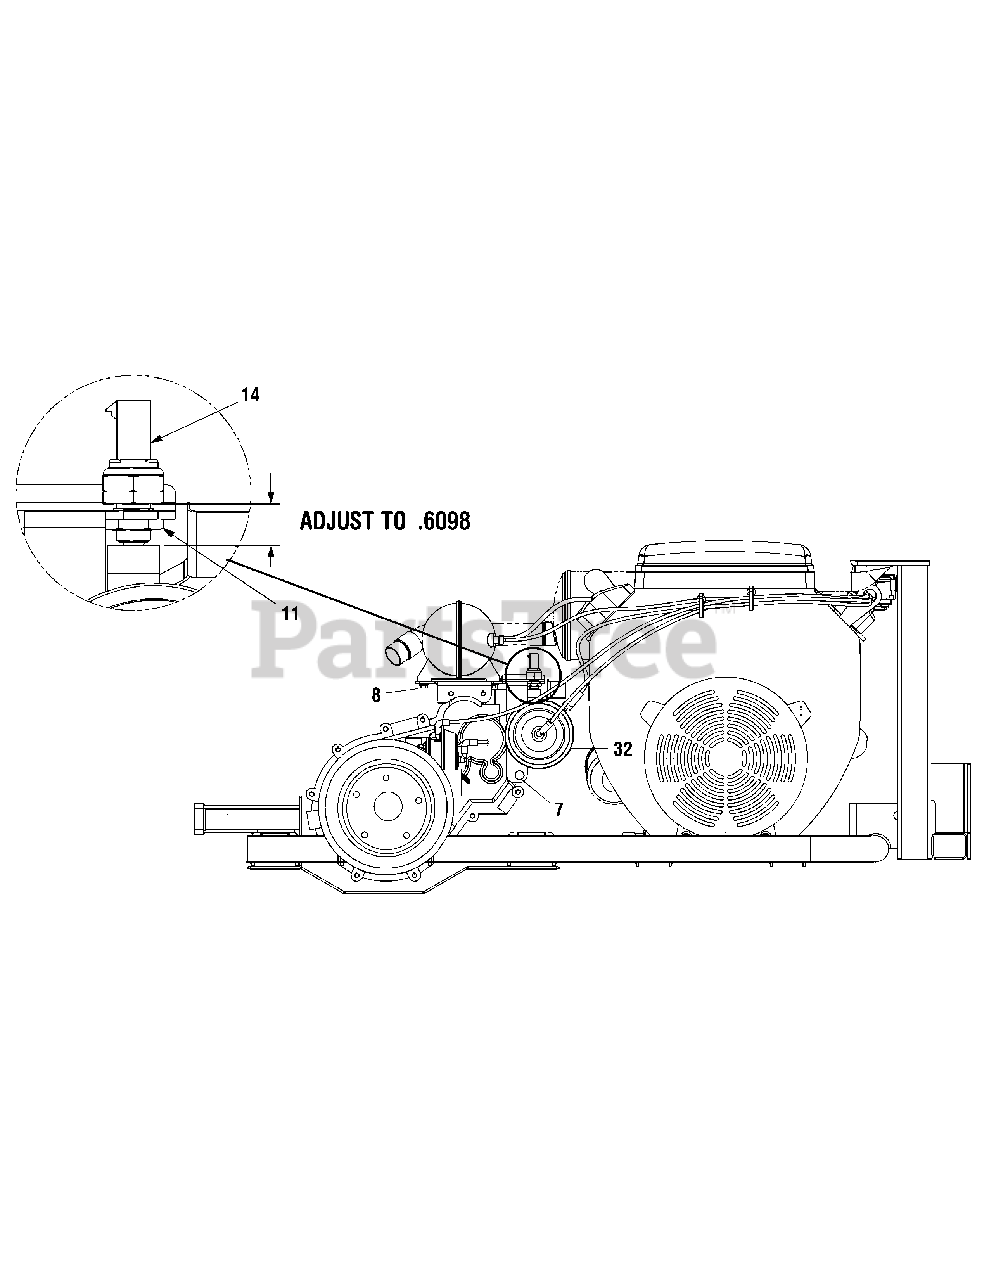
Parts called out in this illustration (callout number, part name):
1	Mounting Bracket, Vacuum Actuator
2	Bracket, Shift
3	Bracket, Vac Relay
4	Screw, 1/4-20 x.5
5	Screw, Hex. #8 - 18 .375
6	Screw, Set, 5/16-24 x .50 LG
7	Screw, 5/16-18
8	Screw, 1/4-14
9	Screw, 5/16-18 x .75 Hex
10	Pin, Yoke 1/4
11	Nut, Hex 9/16-18
12	Pin, Cotter 1/16x.750
13	Yoke, 1/4-28
14	Switch, Neutral
15	Solenoid, Kit Vacuum Actuator
16	Self Threading Nut
17	Clip, Panel Retainer
18	Cable Tie
19	Arm, Shift
20	Hose, Kohler
21	Hose, Manifold Vacuum
22	Hose, Actuator Vacuum
23	Hose, Actuator Vacuum
24	Reservoir, Air
25	Actuator, Vac Differential Lock
26	Differential Lock Vent 3/8 dia.
27	Hose, Vac Differential Lock Supply
28	Cover, Solenoid
29	Flat Washer, .330 x .687 x .030
30	Flat, Washer, .188 x .437 x .042
31	Actuator, Vacuum Shift
32	Straight Fitting
